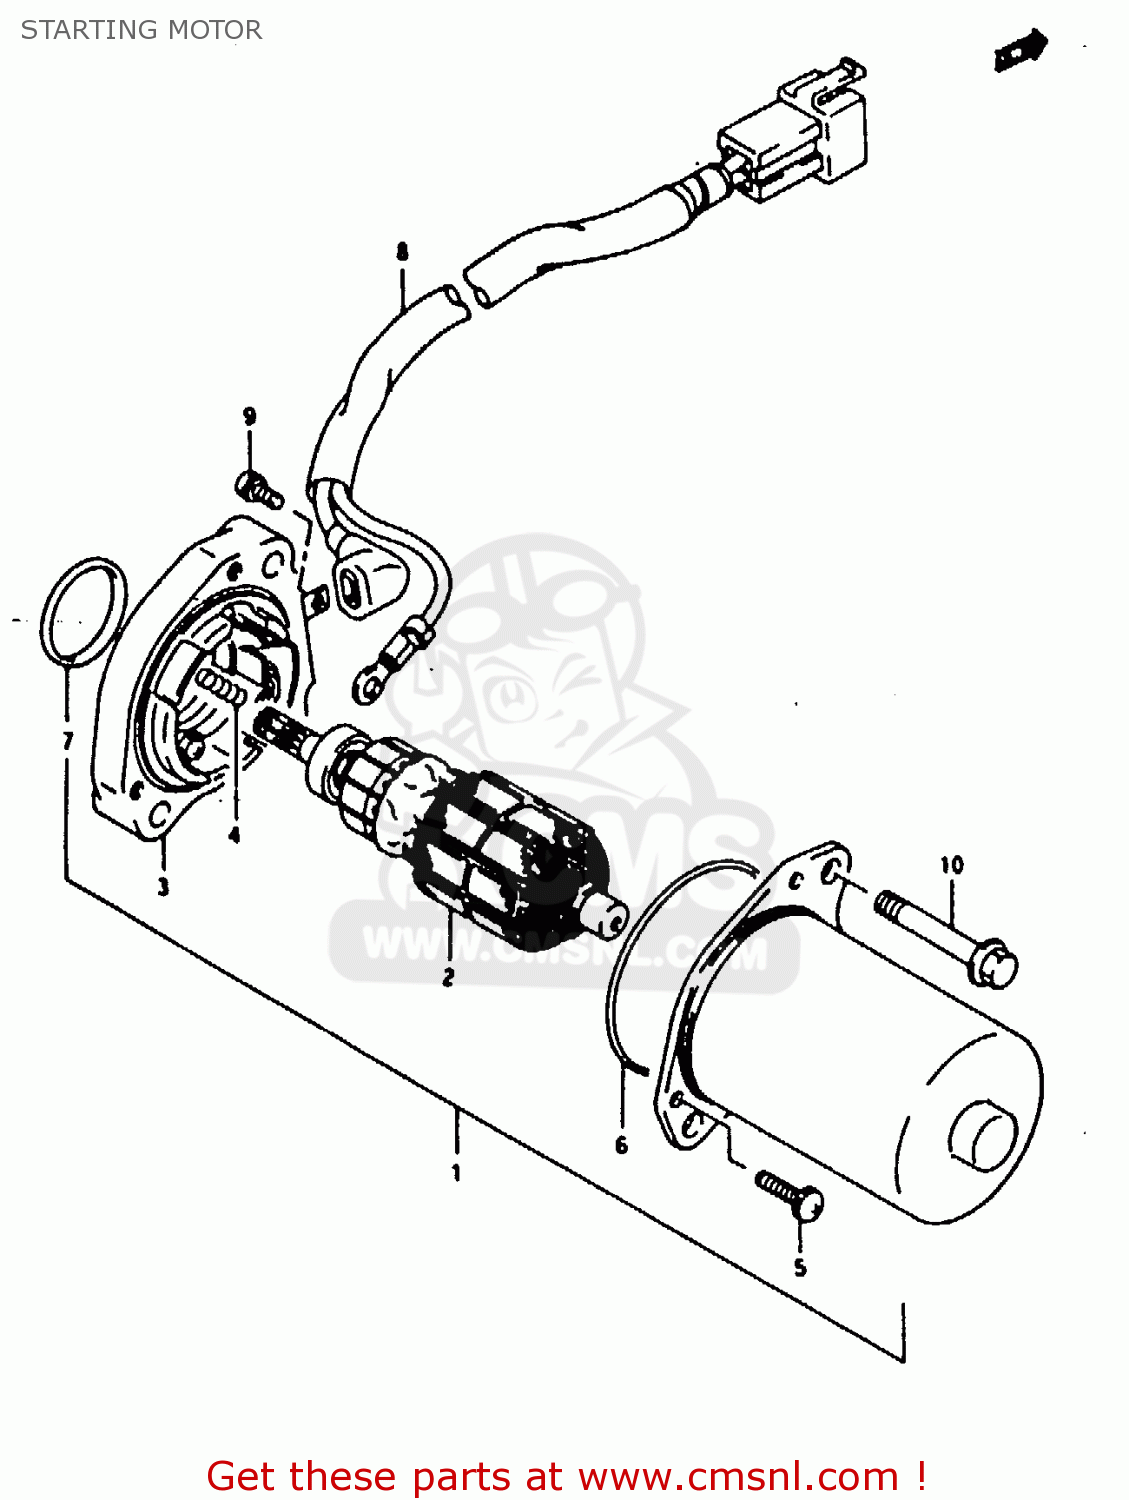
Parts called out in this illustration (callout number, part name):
1	MOTOR,STARTING
2	ARMATURE
3	HOLDER ASSY,BRUSH
4	SPRING
5	SCREW
6	O RING
7	O RING
8	LEAD WIRE, STARTING MOTOR
9	SCREW
10	BOLT
